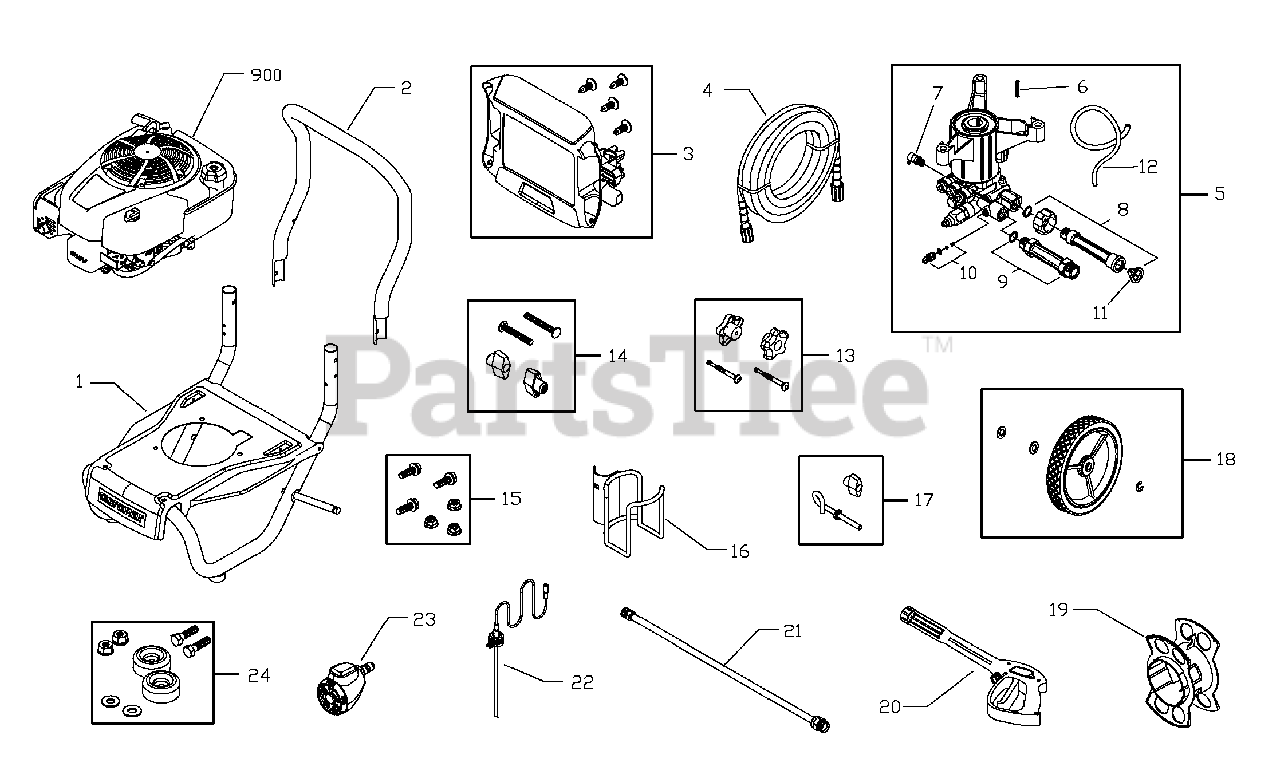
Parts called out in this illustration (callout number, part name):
2	HANDLE
4	HOSE
5	PUMP
7	VALVE, Thermal Relief
8	KIT, Water Inlet
11	FILTER, Garden Hose
12	HOSE, Chemical
15	KIT, Hardware Pump Mounting
20	GUN
21	EXTENSION, QC
23	NOZZLE, QC
24	KIT, Vibration Mount
900	*ENGINE
